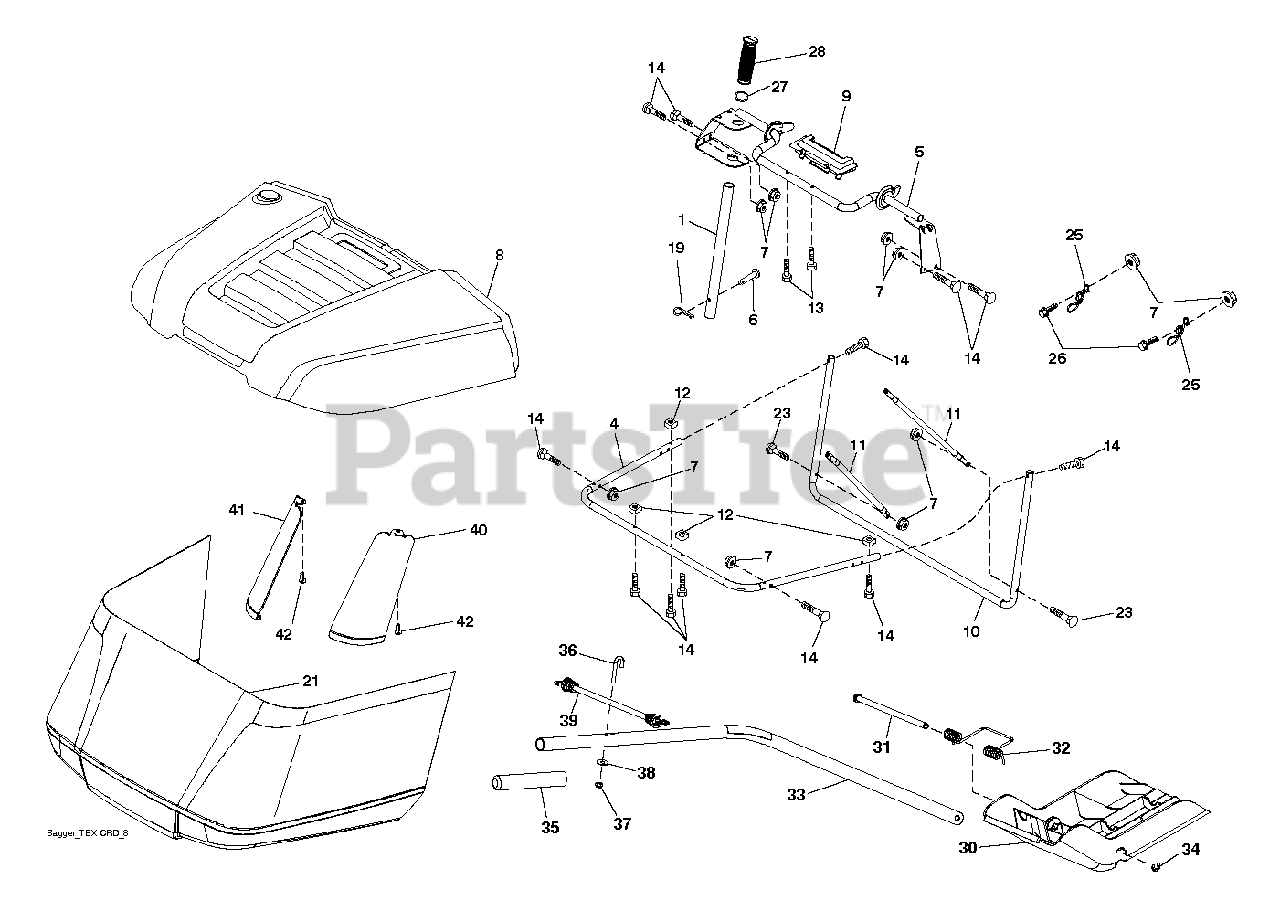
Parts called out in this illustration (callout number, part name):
1	TUBE.PNT.HDL.BAGGER.
6	RIVET,DRILLED
7	NUT T
19	PIN.COTTER.5/16.BOW TI
26	SCREW HEX CRT
28	GRIP.HANDLE.BLACK
34	E-RING.5/16"
38	WASHER
